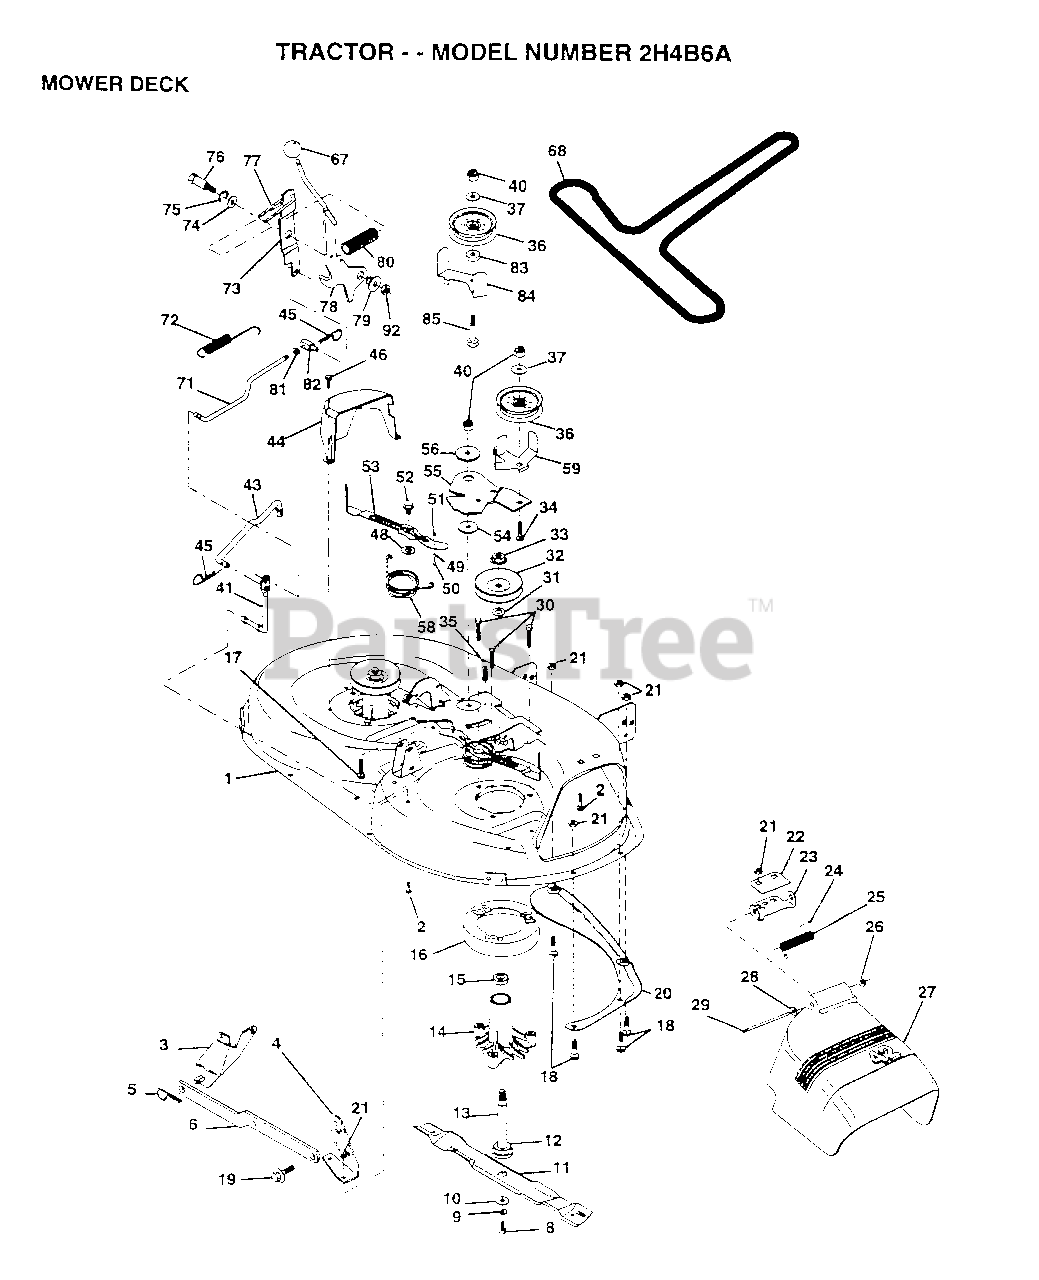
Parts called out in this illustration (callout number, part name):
1	DECK.WELD.42.
2	BOLT
3	BRKT ASM SWAY BAR
4	BRKT DECK SW BAR
8	BLADE BOLT
10	WASHER.HARD.BLADE
11	"BLADE.42"" HIPERF"
12	BEARING.BALL
14	HSG ASM MANDREL
15	BEARING
16	STRIPPER RND MWR
17	BOLT RDHD 3/8-16
18	BOLT
19	BOLT SHD 5/16-18
22	STIFFENER BRKT
23	DEFLECTOR BRKT
24	CAP-SLEEVE LT
25	SPRING TORSION
26	NUT PUSH M
27	DEFLECTOR.SHIELD
28	WASHER
29	HINGE ROD
31	WASHER
34	BOLT
35	XMAS TREE FASTNER
36	FLAT IDLER PULLEY
37	WASHER
41	PIVOT ROD
43	ROD CLUTCH W/NIBS
44	GUARD MAND LH BLK
45	RETAINER M
46	SCREW.1/4-20X5/8
48	HARD SMALL WASHER
50	SHOULDER BOLT
51	LOCKNUT
52	BOLT.SHLD.5/16-18
53	BRAKE PAD ARM ASM
54	HARDENED WASHER
56	SPACER RETAINER
58	SPRING TORSN BRAK
59	GUARD IDLER TUV
67	KNOB T(3/8 HOLE)
68	BELT.V.T-PATH
71	ROD CLUTCH 38/42
72	RETURN SPRING
73	CLUTCH ARM SECOND
74	WASHER
75	RING
76	SHOULDER BOLT
77	SPRING KEEPER
79	BUSHING
81	NUT
82	TRUNION ADJ
83	WASHER
85	BOLT
92	NUT
